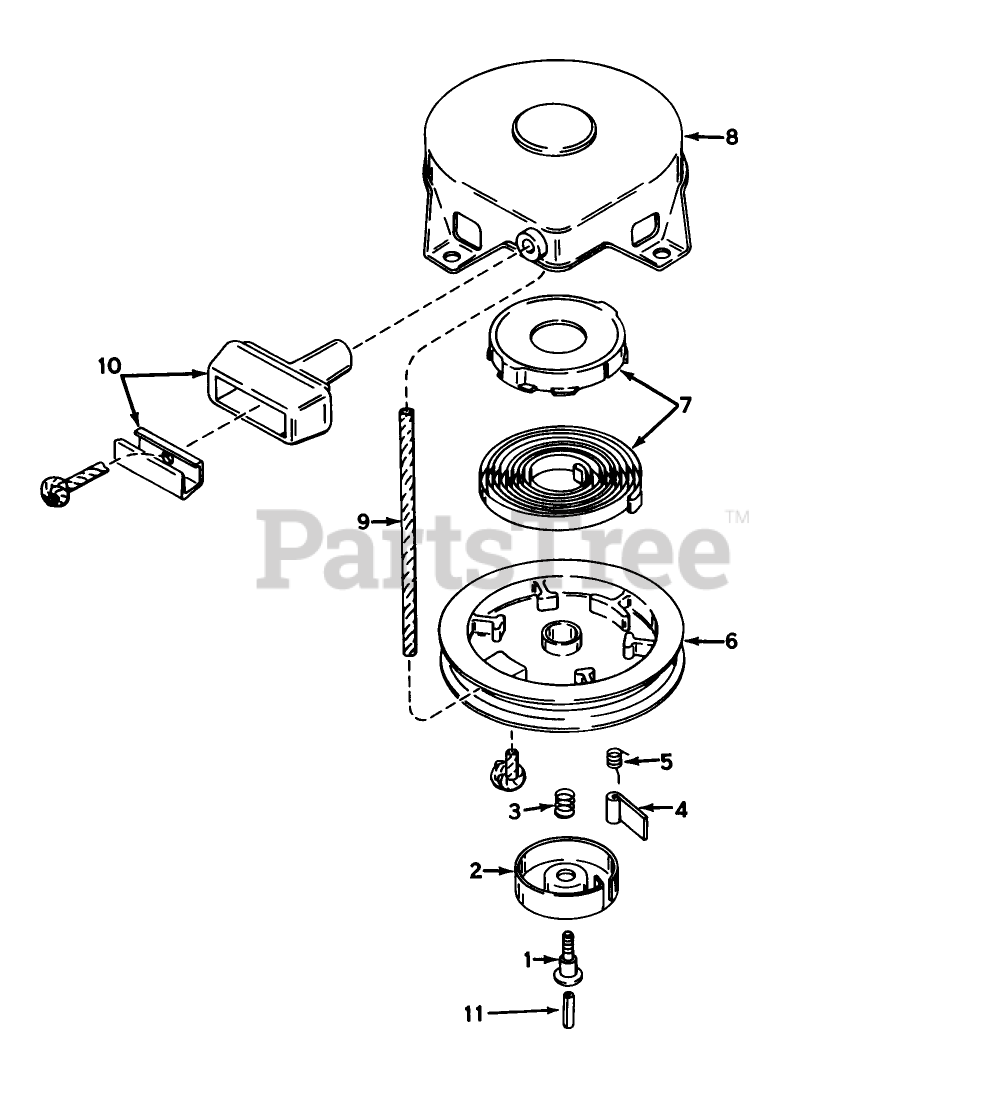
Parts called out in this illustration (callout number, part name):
1	Screw
2	Retainer
3	Spring-Brake
4	Dog-Starter
5	Spring-Dog
6	Pulley
7	Spring Keeper Assy
8	Housing Assy., Starter (Incl. Ref. #1)
9	Rope-Starter
10	Assy., Starter
11	Centering
